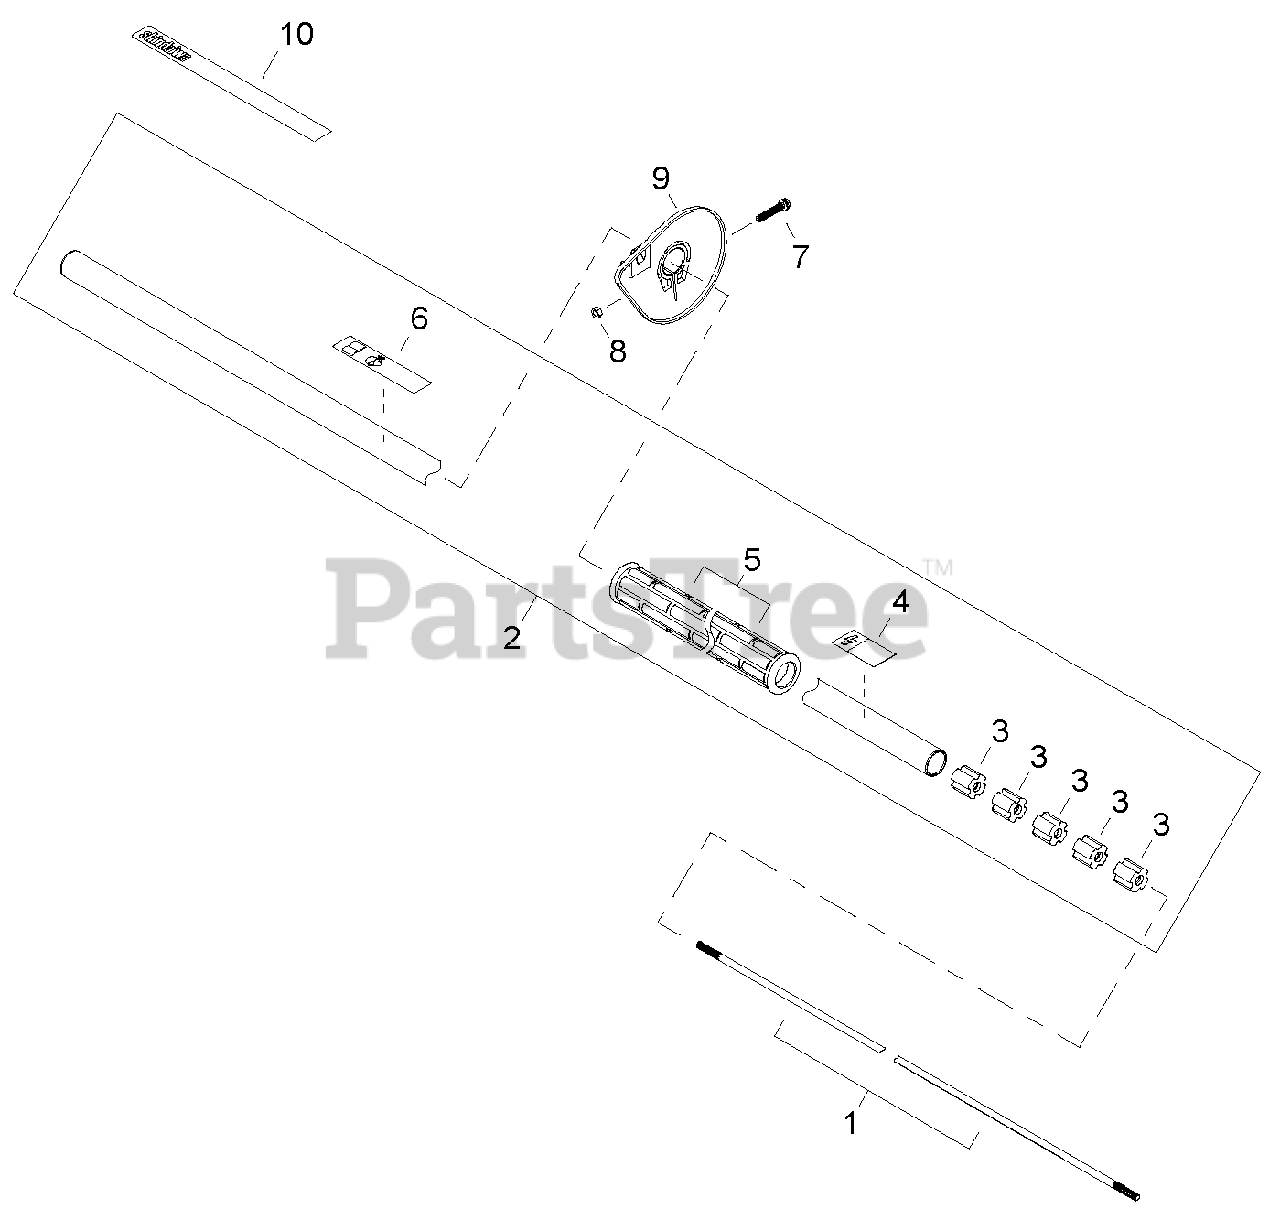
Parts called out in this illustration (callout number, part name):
2	MAIN PIPE ASSY WITH GRIP
3	BUSHING
4	LABEL, HIGH VOLTAGE
5	GRIP, FRONT
6	LABEL, CAUTION
7	SCREW M5×30
8	NUT M5
9	GUARD, HAND
9-1	MAINSHAFT
10	LABEL, SHINDAIWA PROFESSIONAL
